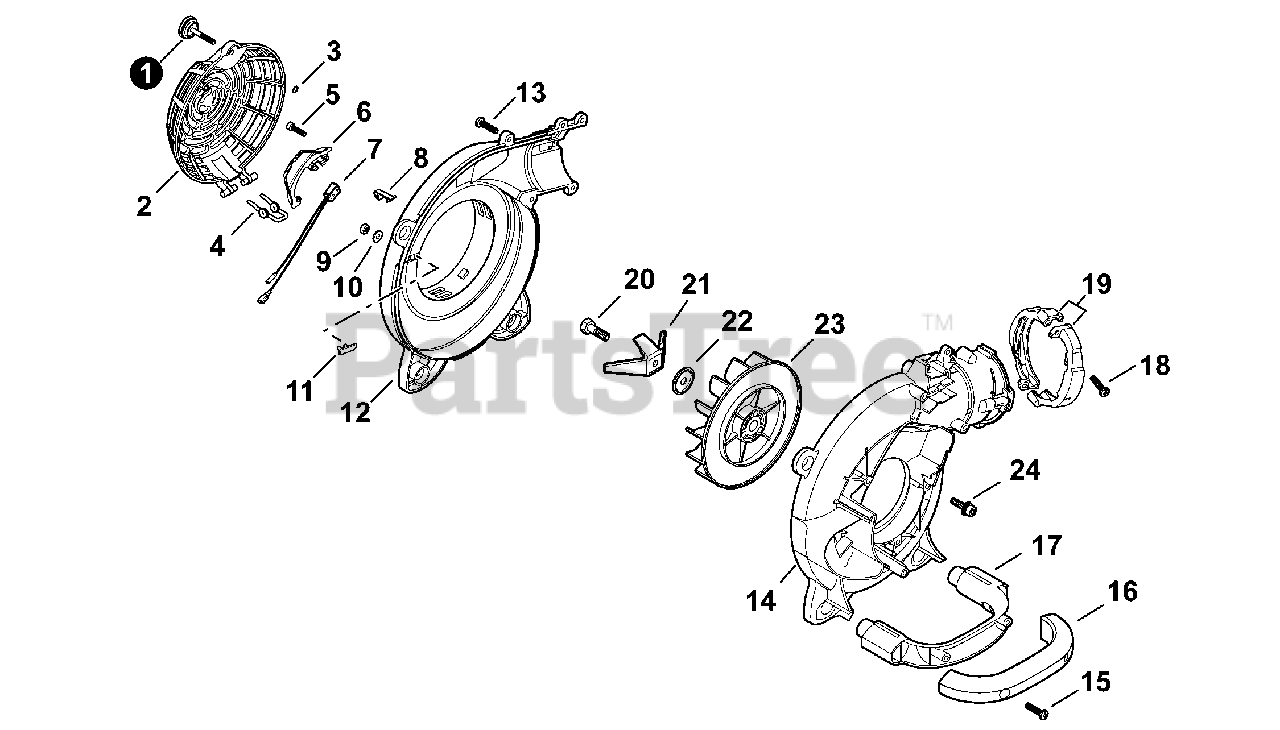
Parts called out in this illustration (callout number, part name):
1	THUMBSCREW
2	GUARD, FAN
3	O-RING 3
4	SPRING, TORSION
5	SCREW 4×16
6	BRACKET, SWITCH
7	SWITCH, SAFETY
8	LEVER, ACTUATOR
9	NUT, LOCK M5
10	WASHER 5.5×12×0.8
12	COVER, FAN
13	SCREW, TAPPING 5×20
14	CASE, FAN
15	SCREW, TAPPING 5×20
16	COVER, HANDLE
17	HANDLE, REAR
18	SCREW, TAPPING 5×20
19	COLLAR, LOCKING
20	BOLT 8×15
21	CUTTER, SHREDDER
22	WASHER 8.2×31×0.8
23	FAN
24	BOLT 4×20
